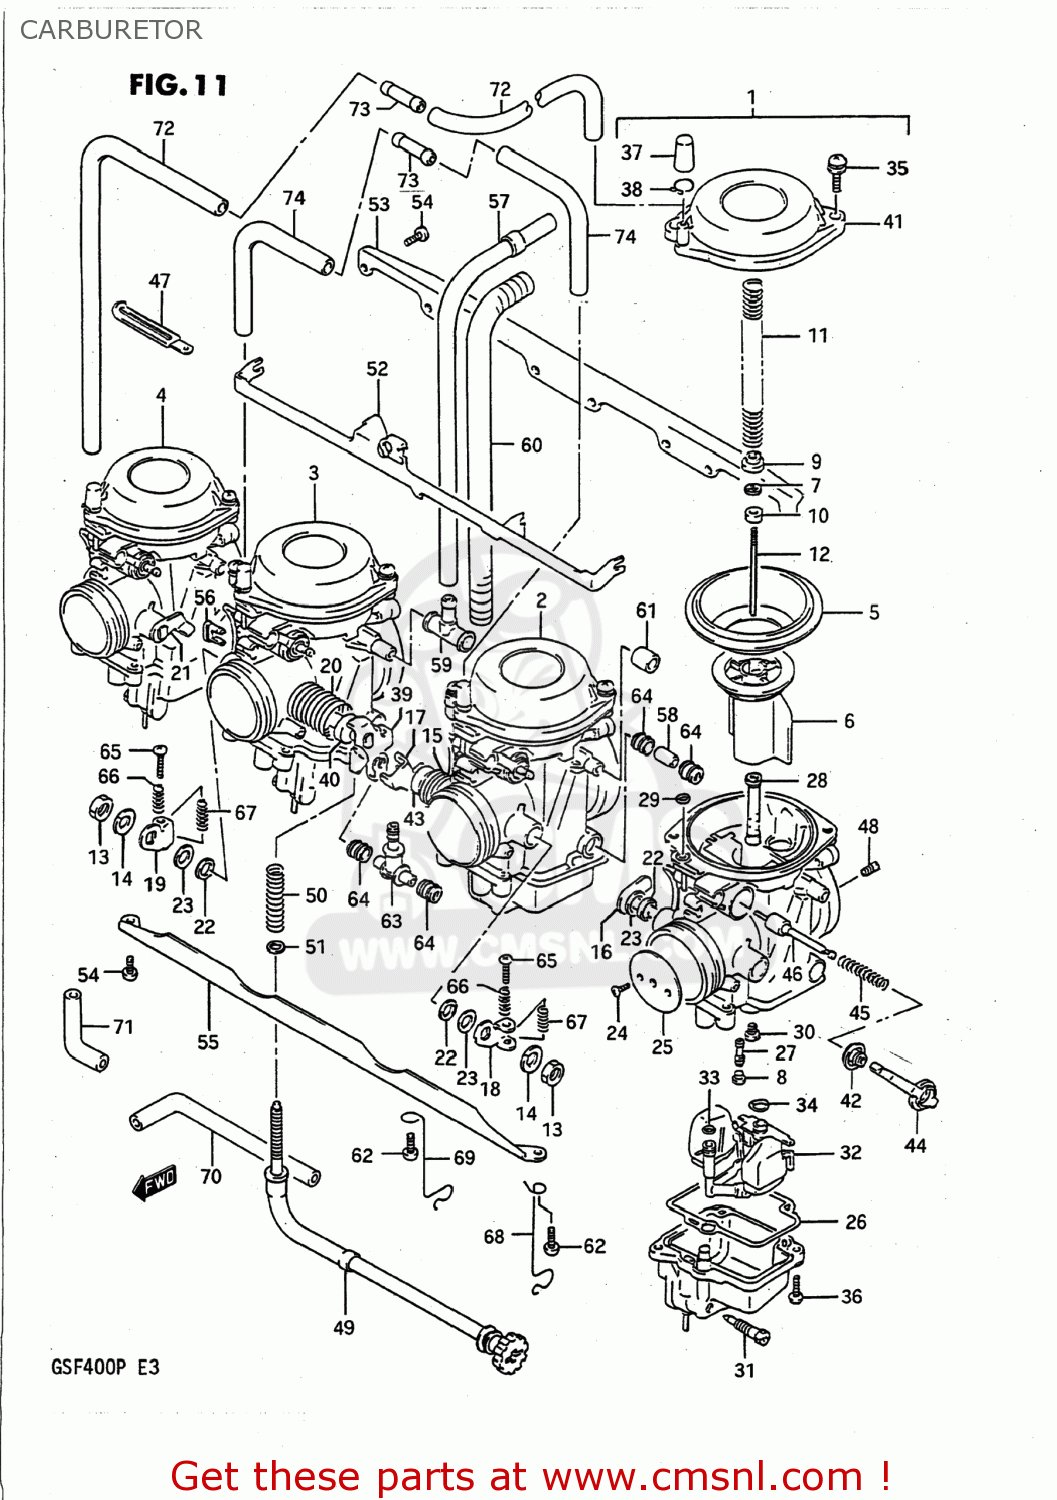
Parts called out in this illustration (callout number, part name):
1	CARBURETOR ASSEMBLY,LEFT
2	CARBURETOR ASSEMBLY,MIDDLE,LEFT
3	CARBURETOR ASSEMBLY,MIDDLE,RIGHT
4	CARBURETOR ASSEMBLY,RIGHT
5	DIAPHRAGM
6	VALVE,PISTON
7	CLIP
8	PLUG
9	RING
10	RING
11	SPRING
12	NEEDLE,JET(5EZ74)
13	NUT
14	WASHER,LOCK,8.
15	SPRING
16	SHAFT ASSEMBLY
17	SHAFT ASSEMBLY
18	LEVER
19	LEVER,THROTTLE
20	SPRING
21	SHAFT ASSEMBLY
22	SEAL
23	GASKET,THROTTLE SHAFT (NAS)
24	SCREW
25	VALVE,THROTTLE (130)
26	GASKET,FLOAT CHAMBER (NAS)
27	JET,PILOT(32.5)
28	JET,NEEDLE(O-9)
29	O RING
30	JET,MAIN(105)
31	SCREW
32	FLOAT/NEEDLE VALVE ASSY
33	O RING
34	O-RING,NEEDLE VALVE
35	SCREW
36	SCREW
37	CAP
38	CLIP
39	SHAFT ASSEMBLY
40	RING
41	COVER,DIAPHRAGM
42	CAP,STARTER
43	RING
44	HOLDER,GUIDE
45	SPRING
46	PLUNGER ASSY
47	CLAMP
48	JET,AIR
49	ADJUSTER ASSEMBLY
50	SPRING
51	WASHER
52	LEVER
53	PLATE
54	SCREW
55	PLATE
56	HOLDER
57	HOSE
58	PIPE
59	3 WAY
60	PROTECTOR,HOSE
61	HOSE
62	SCREW
63	NIPPLE
64	SEAL
65	SCREW
66	SPRING
67	SPRING
68	CLIP
69	CLIP
70	HOSE
71	HOSE ASSEMBLY
72	HOSE
73	NIPPLE
74	HOSE
